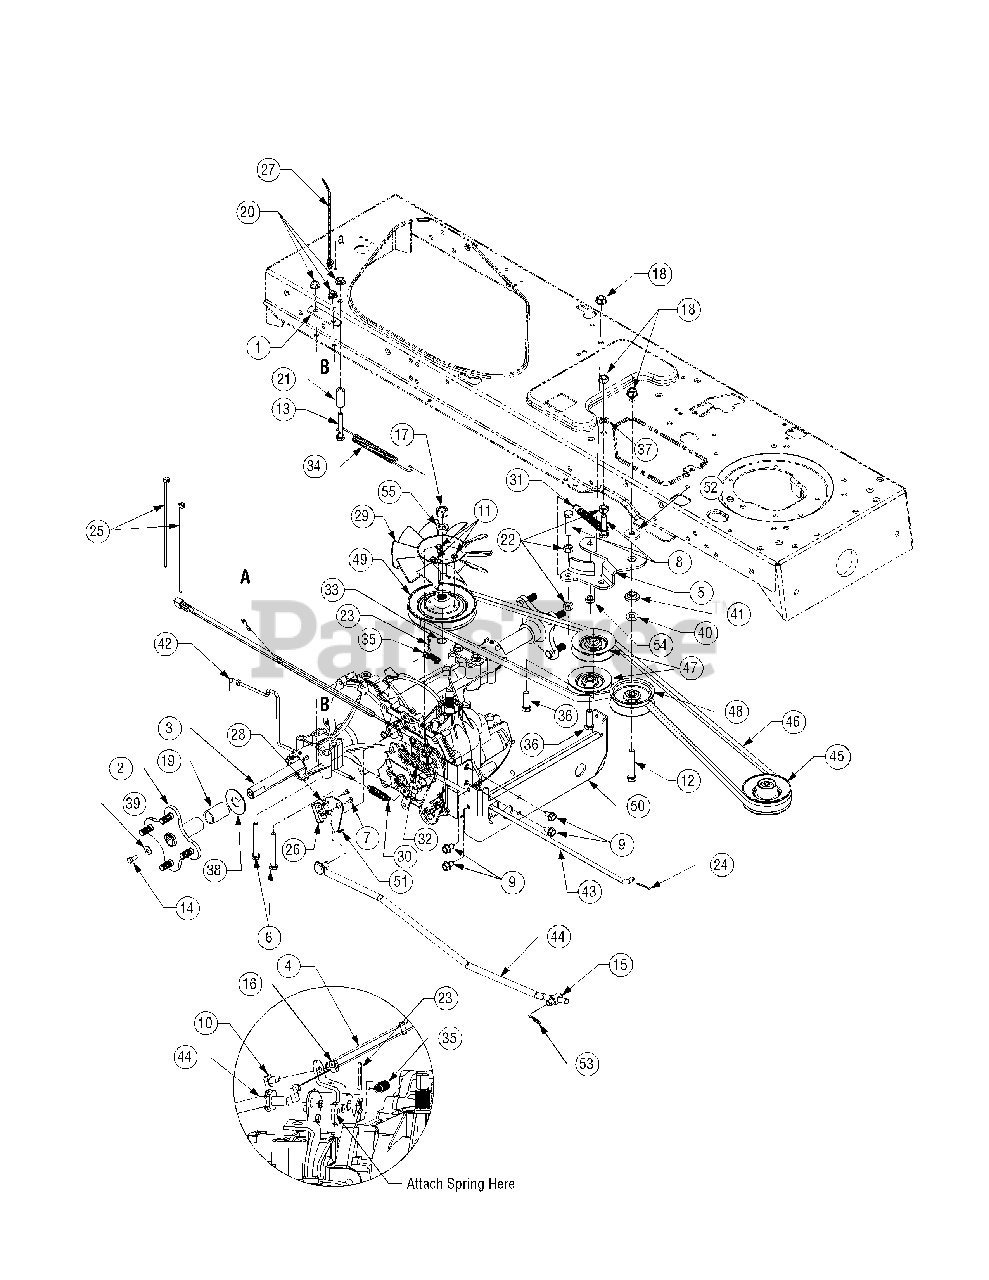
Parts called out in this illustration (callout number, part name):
2	Hub Assembly, Wheel
3	Transmission, Hydrostatic
3	Transmission, Hydrostatic w/ Drain
4	Harness Assembly, Ground & Reverse
6	Hex Cap Screw, 5/16-18,3.5, Gr5
7	Screw, #8-18, 0.500
8	Hex Cap Screw, 3/8-16, 1.50, Gr5
9	Screw, 5/16-12, 0.75
10	Screw, 1/4-20, 0.5
11	Screw, #12-24, 0.375
12	Hex Cap Screw, 3/8-16, 2.25, Gr5
13	Hex Cap Screw, 5/16-18, 1.25, Gr5
14	Hex Cap Screw, 5/16-24 x .750
15	Ferrule, 3/8-24 x .375 Dia
16	Nut, Hex Lock, 1/4-20
17	Nut, Hex, 1/2-20, Gr5
18	Nut, Nylon Lock, 3/8-16
19	Sleeve, 2.4"
20	Nut, Nylon Lock, 5/16-18, Gr5
21	Spacer, 1"
22	Nut, Hex, 3/8-16, Gr8
23	Pin, Cotter, .072 Dia. x 1.13 Lg
24	Pin, Cotter, 3/32, 1.0
25	Cable, Tie, 3/16 x .05 x 7.4
26	Switch, Spring, Short
27	Tie, Cable, Push Mount 7.5 Lg
28	Plate, Insulator Nut
29	Fan, Blade, 10"
30	Spring, .48 OD x 2.03 Extension
31	Spring, Extension, .50 Dia x 3.97 Lg
32	Spring, Extension, .59 OD x 4.00 Lg
33	Ring, Wire
34	Spring, Extension, .500 Dia x 7.0
35	Spring, Extension, 3/8 OD x 1.44
36	Screw, 3/8-16, 1.25
37	Washer, Lock, 3/8 , Regular Duty
38	Washer, Flat, .755 x 1.92 x .060
39	Belle Washer
40	Washer, Flat, .407 x .812 x .135
41	Spacer, Shoulder, 1.00 x .38 x .38
42	Rod, Hydro Bypass
43	Rod, Brake, Hydro
44	Rod, Control, Hydro
45	Pulley, Engine, 3.56 Dia.
46	Belt, V Type, Poly
47	Pulley, Idler, V Type x 3.06 Dia
48	Pulley, Idler, Flat 2.75 OD
49	Pulley, Engine, 4.11Dia.
52	Washer, Flat, .38 x 1.92 x .060
53	Pin, Cotter, 3/32, .750
54	Spacer, .38 x .625 x .21
55	Washer, Lock, 1/2
